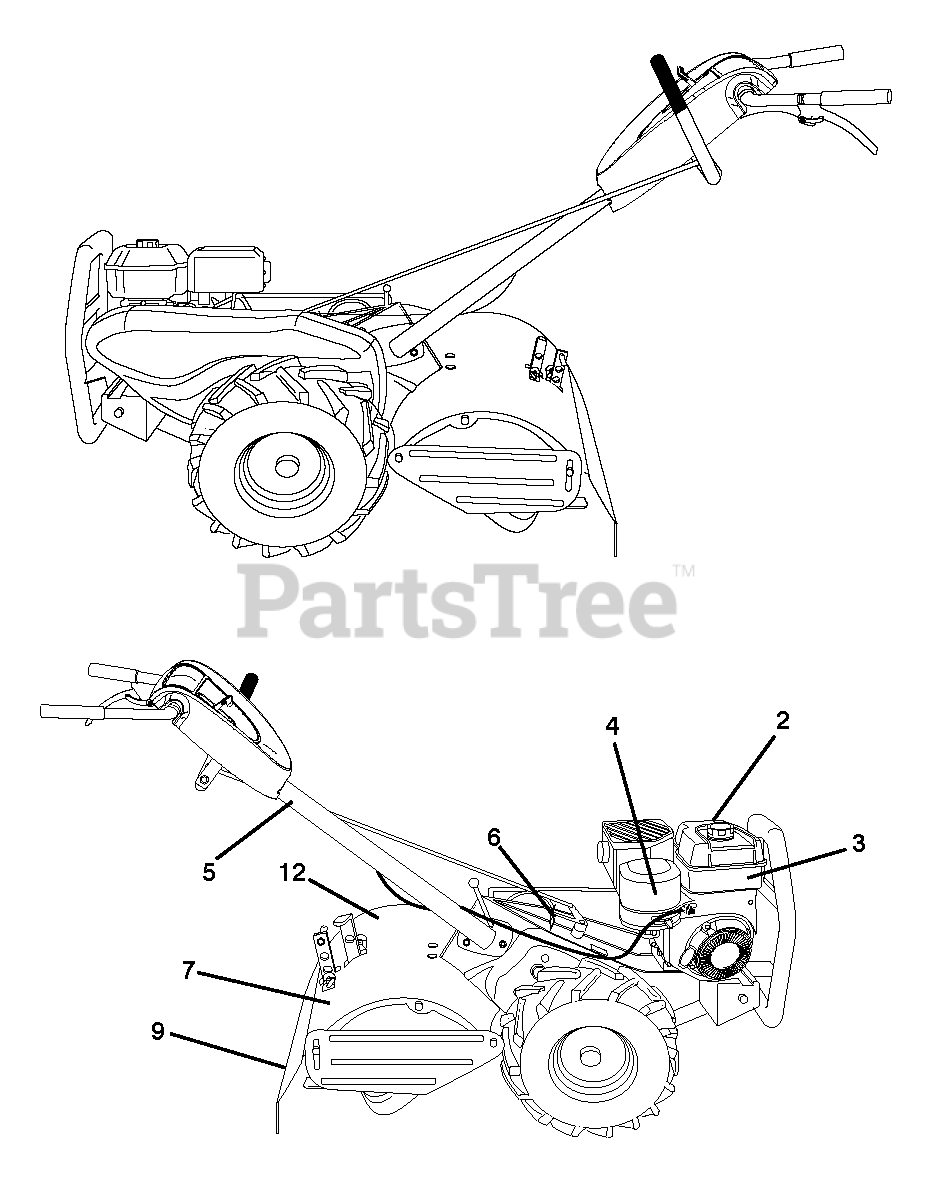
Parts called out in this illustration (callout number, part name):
2	DECAL,ETHANOL E85 WARNING
3	DECAL, WARNING SPARK ARRESTOR
4	DECAL.B&S.950S
5	DECAL TI (2 2)
6	DECAL.SHIFT.INDICATOR.DRT
7	DECAL.REVERSE.HUSQ.TILLER
9	DECAL.DRT.WARN.ENG/F
12	DECAL.FOWARD.HUSQ.TILLER
